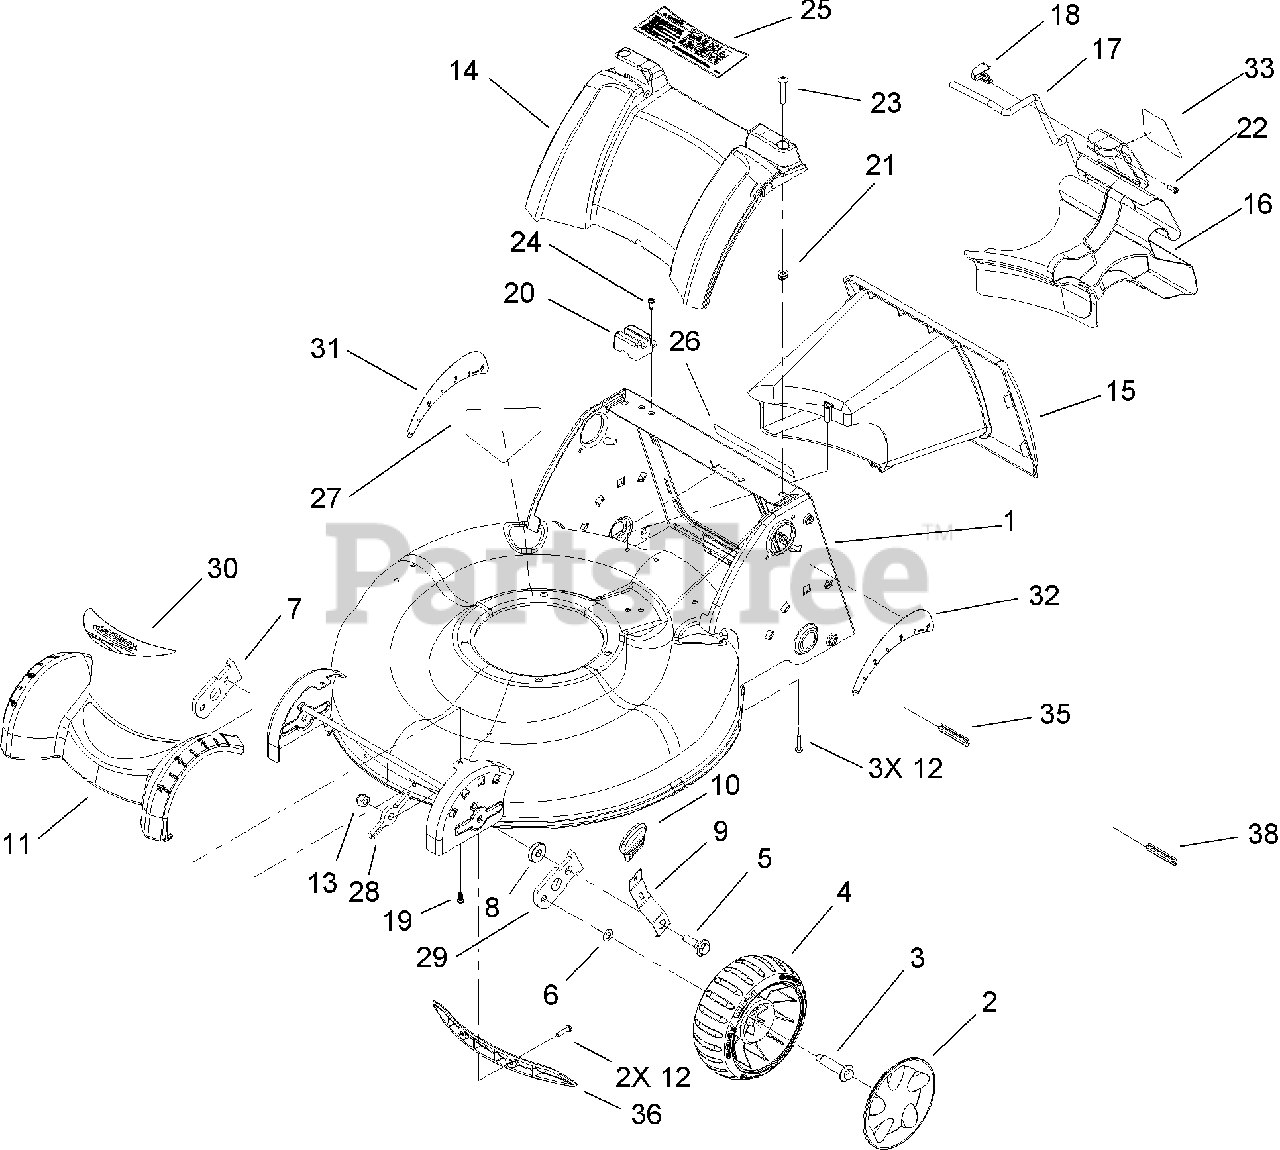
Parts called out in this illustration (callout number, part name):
1	HOUSING ASM
2	COVER-WHEEL, 7IN
3	BOLT-SHOULDER
4	7IN WHEEL ASM
5	BOLT-SHOULDER
7	ARM-PIVOT, RH
9	ARM-SPRING
10	KNOB-LEVER, HOC
11	COVER-FRONT
12	SCREW-PLASTITE
13	NUT-LOCK, NI
14	COVER-REAR
15	TUNNEL
16	PLUG-CHUTE
17	LATCH-PLUG
18	RETAINER-LATCH
19	SCREW-PLASTITE
20	MODULE-SWITCH
21	NUT-CLIP
22	SCREW-PPH
23	SCREW-PTH
24	SCREW-THREAD FORMING
25	DECAL-DANGER
26	DECAL-SAFETY
27	DECAL-DANGER
28	WASHER-SUPPORT, FRONT
29	ARM-PIVOT, LH
31	DECAL-HOC, RH
32	DECAL-HOC, LH
35	STRIP-EDGE
36	INSERT-HOUSING
38	STRIP-EDGE
